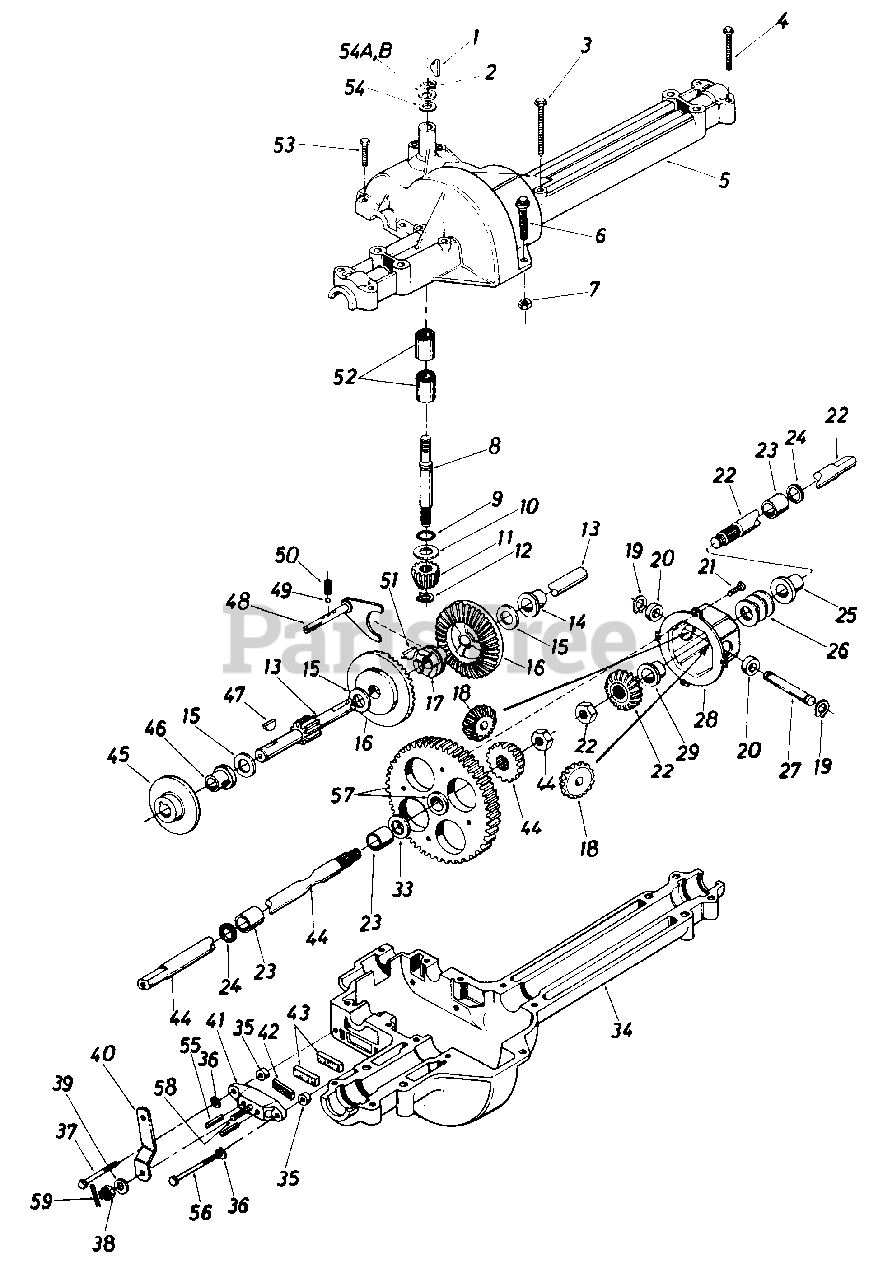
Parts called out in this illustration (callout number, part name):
1	#4 Hi-Pro Key 3/32 x 5/8" Dia.
2	Snap Ring .625" Shaft
3	Hex Bolt 1/4-20 x 1.75" Lg.
4	Hex Bolt 5/16-18 x 2.5"
5	Upper Housing
6	Hex Fl-Bolt 1/4-20 x .88" Lg.
7	Hex Nut 1/4-20 Thd.
8	Input Shaft
9	Square Seal 5/8" I.D.
10	Thrust Washer 5/8" I.D. x 1.25" O.D.
11	Pinion Input 14T
12	Retaining Ring 7/16" Ext.
13	Drive Shaft
14	Flange Brg. 5/8" I.D. x 3/4" Lg.
15	Fl-Wash.
16	Bevel Gear 42T
17	Clutch Collar
18	Miter Gear 15T (H.D.)
19	Snap Ring
20	Thrust Bearing 1/2" I.D. x l.0" O.D.
21	Pan Head Scr. 1/4-20 x .50" Lg. w/Patch
22	Axle R.H. Ass'y.-Kit
23	Sleeve Bearing 3/4" I.D. x 1.0" Lg.
24	Oil Seal 3/4" I.D.
25	Flange Bearing 3/4" I.D. x 15/16" Lg.
26	Fl-Wash. .760" I.D. x 1.49" O.D.
27	Cross Shaft
28	Differential Housing Ass'y.
33	Fl-Wash. .760" I.D. x 1.49" O.D.
34	Lower Housing
35	Spacer .53" O.D. x 3/8" Lg.
36	L-Wash. 1/4" I.D.
37	Hex Bolt 1/4-20 x l.50" Lg. (Grade 5)
38	Castle Nut 5/16-24 Thd.
39	Fl-Wash. .344 I.D. x .875" O.D.
40	Actuating Arm
41	Brake Yoke
42	Puck Plate
43	Brake Puck
44	Axle L.H. Ass'y.-Kit
45	Brake Disc
46	Flange Bearing 5/8" I.D. x 15/16" Lg.
47	Woodruff Key 3/16 x 5/8 HT
48	Shift Fork Ass'y.
49	Ball Detent .250" Dia.
50	Spring Detent
51	#9 Hi-Pro Key 3/16" x 1/4" Dia. HT
52	Needle Brg. 5/8" I.D. x 1/2" Lg.
53	Hex Bolt 1/4-20 x 1.00" Lg.
54	Fl-Wash. 5/8" I.D. x .040
54A	Fl-Wash. 5/8" I.D. x .030
54B	Fl-Wash. 5/8" I.D. x .030
55	Actuating Pin 5/16" Dia.
56	Hex Bolt 1/4-20 x 2.50" Lg. (Grade 5)
57	Differential Gear 72T Ass'y. w/ Bearing
58	Sq. Hd. Bolt 5/16-24 Thd.
59	Cotter Pin 3/32" Dia. x 50" Lg.
